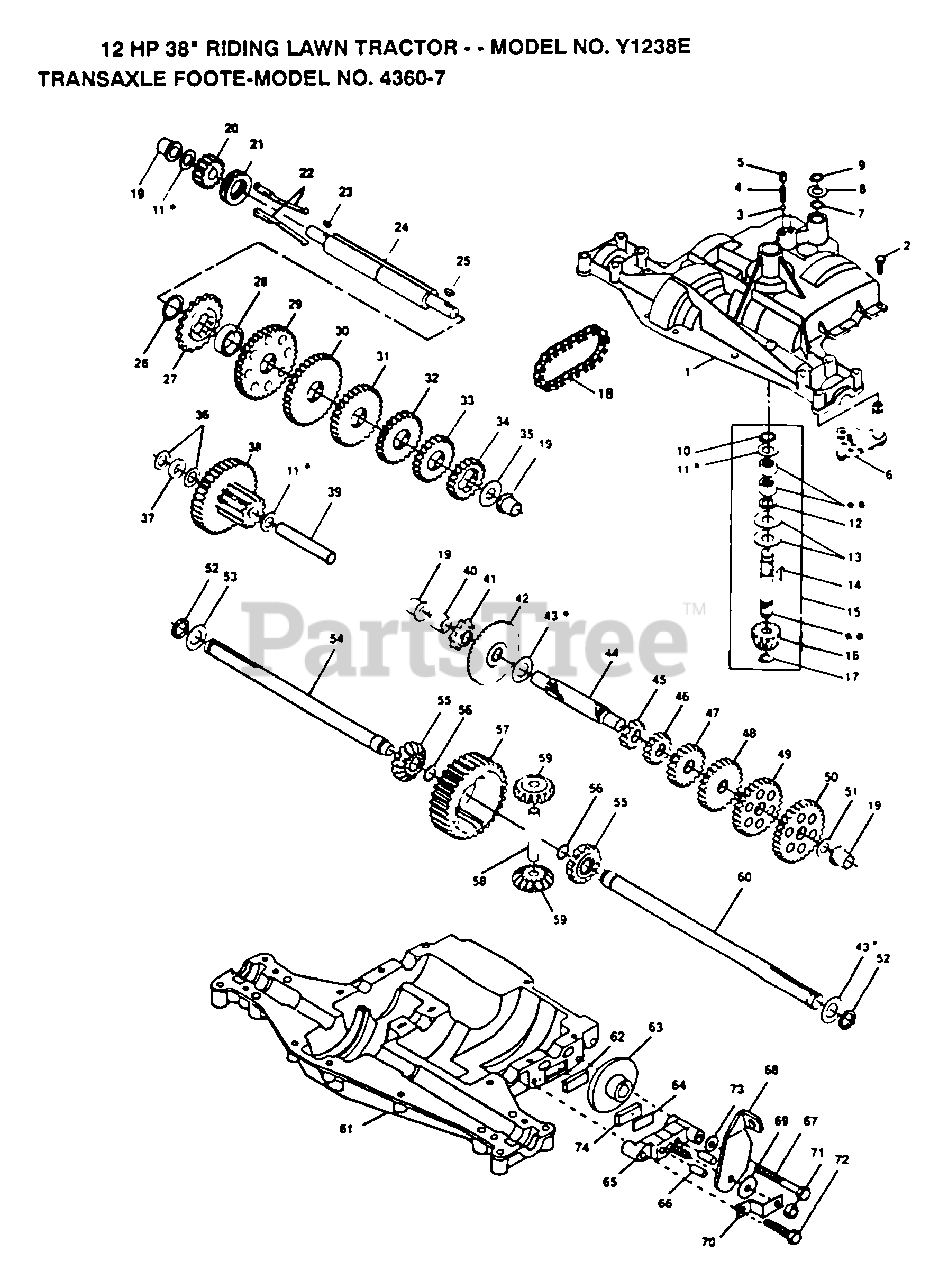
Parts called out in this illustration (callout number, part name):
1	HOUSING UPPER
3	BALL DETENT
4	SPRING, DETENT
5	SCREW, SET
6	ASSY SHIFTER
8	WASHER PLAIN
9	RING RETAINING
10	RING RETAINING
11	WASHER PLAIN
11	WASHER, PLAIN .632 X 1.00 X .026
11	WASHER, PLAIN .632 X 1.00 X .060
13	WASHER, PLAIN .632 X 1.38 X .046
14	KEY WOODRUFF #9
15	ASSY KIT INPUT SHAFT
16	PINION, BEVEL, 14 TEETH
17	RING, RETAINING
18	CHAIN, 24 PITCHES
19	BEARING, FLANGE
20	GEAR SPUR, 14 TEETH
21	COLLAR CLUTCH
22	KEY CLUTCH
23	KEY WOODRUFF #3
24	SHAFT INTERMEDIATE
25	KEY, WOODRUFF, #61
26	RING, RETAINING
27	SPROCKET, 18 TEETH
29	GEAR, SPUR, 37 TEETH
30	GEAR, SPUR, 35 TEETH
31	GEAR, SPUR, 30 TEETH
32	GEAR, SPUR, 25 TEETH
33	GEAR, SPUR, 22 TEETH
35	WASHER, PLAIN .640 X 1.37 X .061
36	WASHER, PLAIN .632 X 1.00 X .026
37	SPACER .630 X 1.00 X .169
38	ASSY GEAR COMB 12&35 TEETH
39	SHAFT IDLER
40	SPACER .635 X .875 X .755
41	SPROCKET, 9 TEETH
42	GEAR, BEVEL, 42 TEETH
43	WASHER PLAIN
43	WASHER, PLAIN .758 X 1.25 X .031
44	SHAFT, DRIVE
45	GEAR, SPUR, 12 TEETH
46	GEAR SPUR, 15 TEETH
47	GEAR, SPUR, 20 TEETH
48	GEAR, SPUR, 25 TEETH
49	GEAR, SPUR, 28 TEETH
50	GEAR, SPUR, 31 TEETH
51	WASHER, PLAIN .632 X 1.00 X .060
53	WASHER PLAIN
54	AXLE LEFT HAND
55	GEAR, MITER, 15 TEETH
56	RING, RETAINING
57	GEAR, SPUR, 32 TEETH
58	SHAFT, CROSS
59	GEAR, MITER, 15 TEETH
60	AXLE, R.H.
61	HOUSING LOWER
62	PUCK, FRICTION
63	DISC, BRAKE
65	JAW, BRAKE
66	PIN, DOWEL
67	SCREW TAPPING
68	LEVER, ACTUATING
69	WASHER, PLAIN .321 X 1.00 X .055
70	BRACKET, ANTI-ROTATION
71	LOCKNUT 5/16-24
72	SCREW TAPPING
73	WASHER PLAIN
74	PUCK, FRICTION
